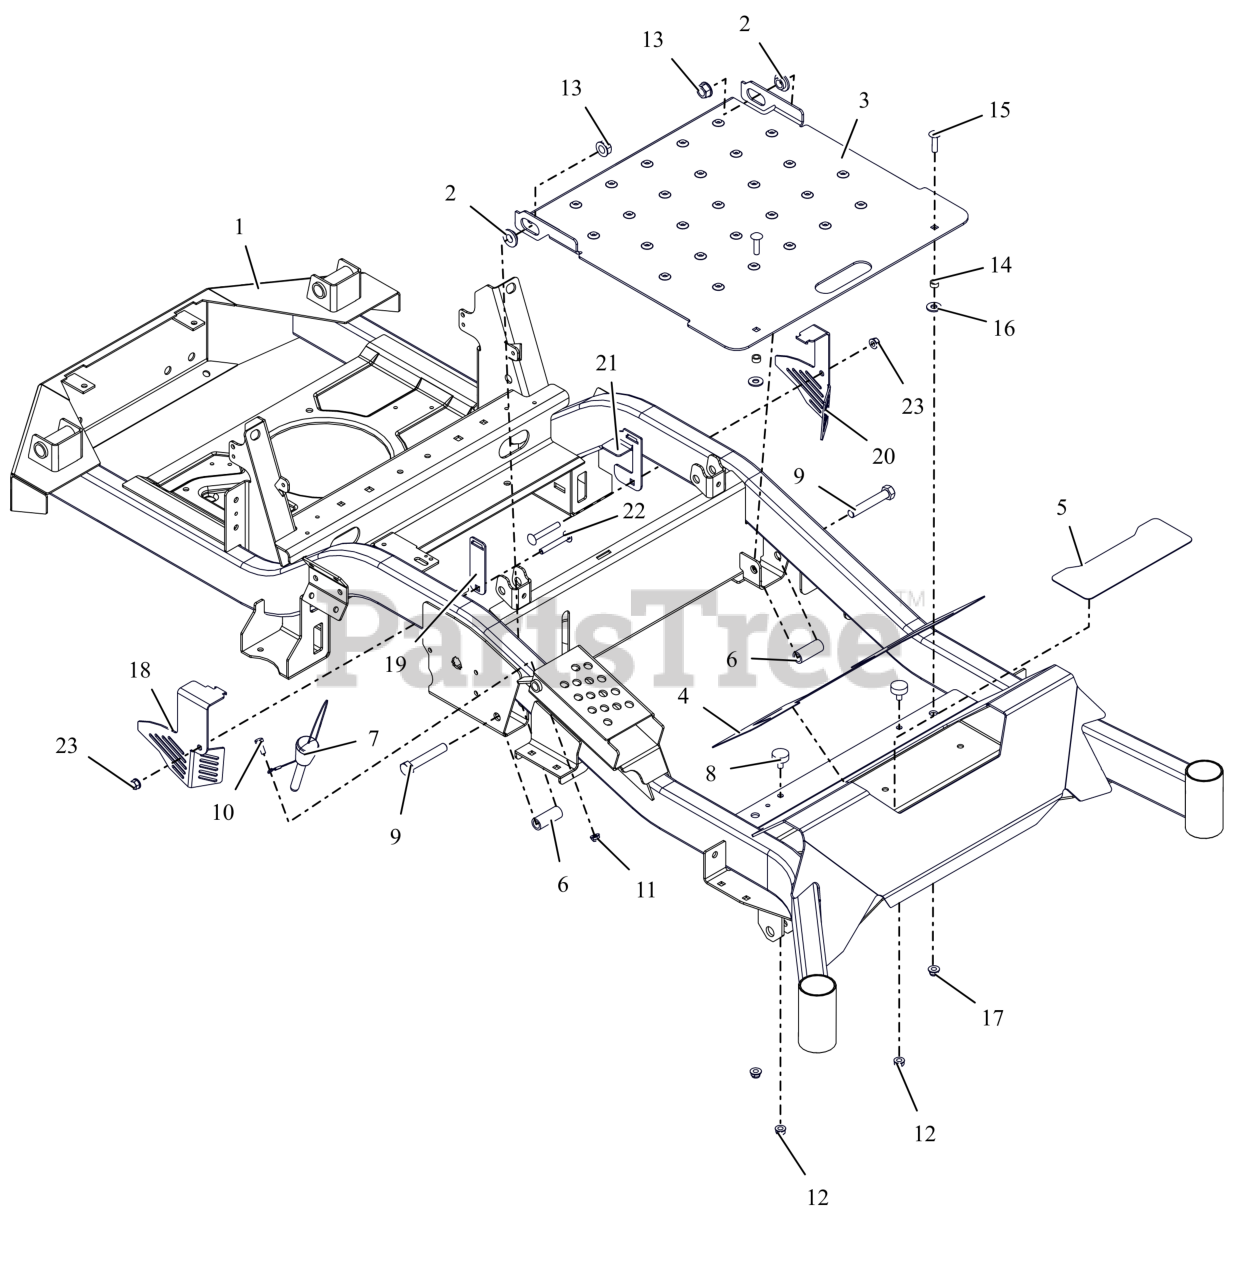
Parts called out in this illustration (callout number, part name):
1	WLDMT, MAIN FRAME -APEX 44-52 (ORANGE)
2	BSHG-FLG .515X.750X.395X1.120
3	PANEL, ACCESS
4	GRIP, FRONT
5	GRIP, STEP
6	SPACER, .515X.75X1.83
7	PIN, MAGNETIC .50X2.50
8	BUMPER, RUBBER
9	BLT, HEX .50-13X3.00 G5 ZCC
10	BLT, HEX .25-20X.75 G5 ZCC
11	NUT,NYL-FLG .25-20 GF ZCC
12	NUT,SPNLK-FLG .31-18 G5 ZCC
13	NUT-LK-TOP-FLG .500-13 GF ZCC
14	BSHG-SLV .344 X .500 X .260
15	BLT, RHSSN.31-18X1.25 G5 ZCC
16	WSHR,FLT .375X.875X.083 ZCC
17	NUT,LK-NYL-FLG .31-18 G5ZC120
18	GUARD, TRANSAXLE FAN - RH
19	BRKT, TRANSAXLE FAN GUARD
20	BRKT, TRANSAXLE FAN GUARD-LH
21	MOUNT, TRANSAXLE GUARD
22	BLT, RHSSN.31-18X2.25 G5 ZCC
23	NUT,LK-CTR-FLG .31-18 GF ZCC
